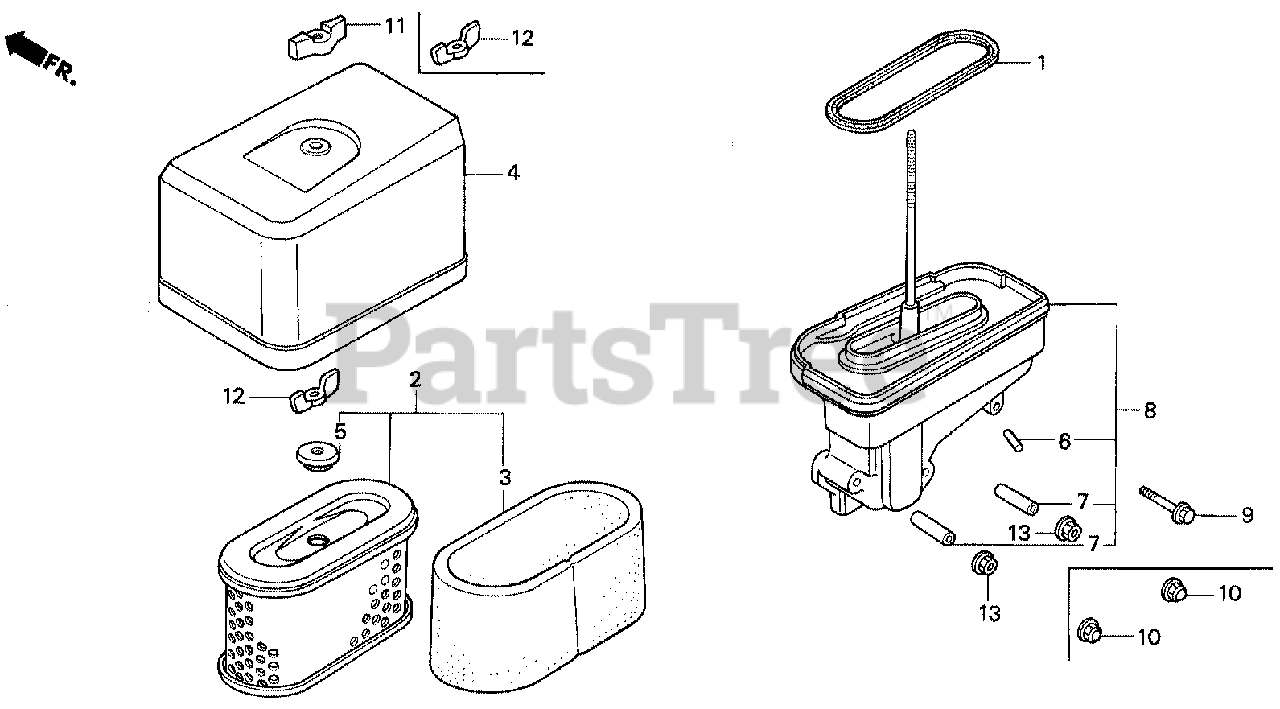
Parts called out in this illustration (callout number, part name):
1	GASKET, ELBOW
2	ELEMENT, AIR CLEANER (Honda Code 3133808). (METAL BASE)
2	ELEMENT, AIR CLEANER (Honda Code 5248299). (METAL BASE)
3	FILTER (OUTER)
4	COVER, AIR CLEANER (DUAL)
5	GROMMET, AIR CLEANER
6	COLLAR, AIR CLEANER
7	COLLAR, AIR CLEANER
8	ELBOW, AIR CLEANER
9	BOLT, FLANGE (6X35)
10	NUT, CAP (6MM)
11	WINGNUT (6MM)
12	WINGNUT, TOOL BOX SETTING
13	NUT, FLANGE (6MM)
